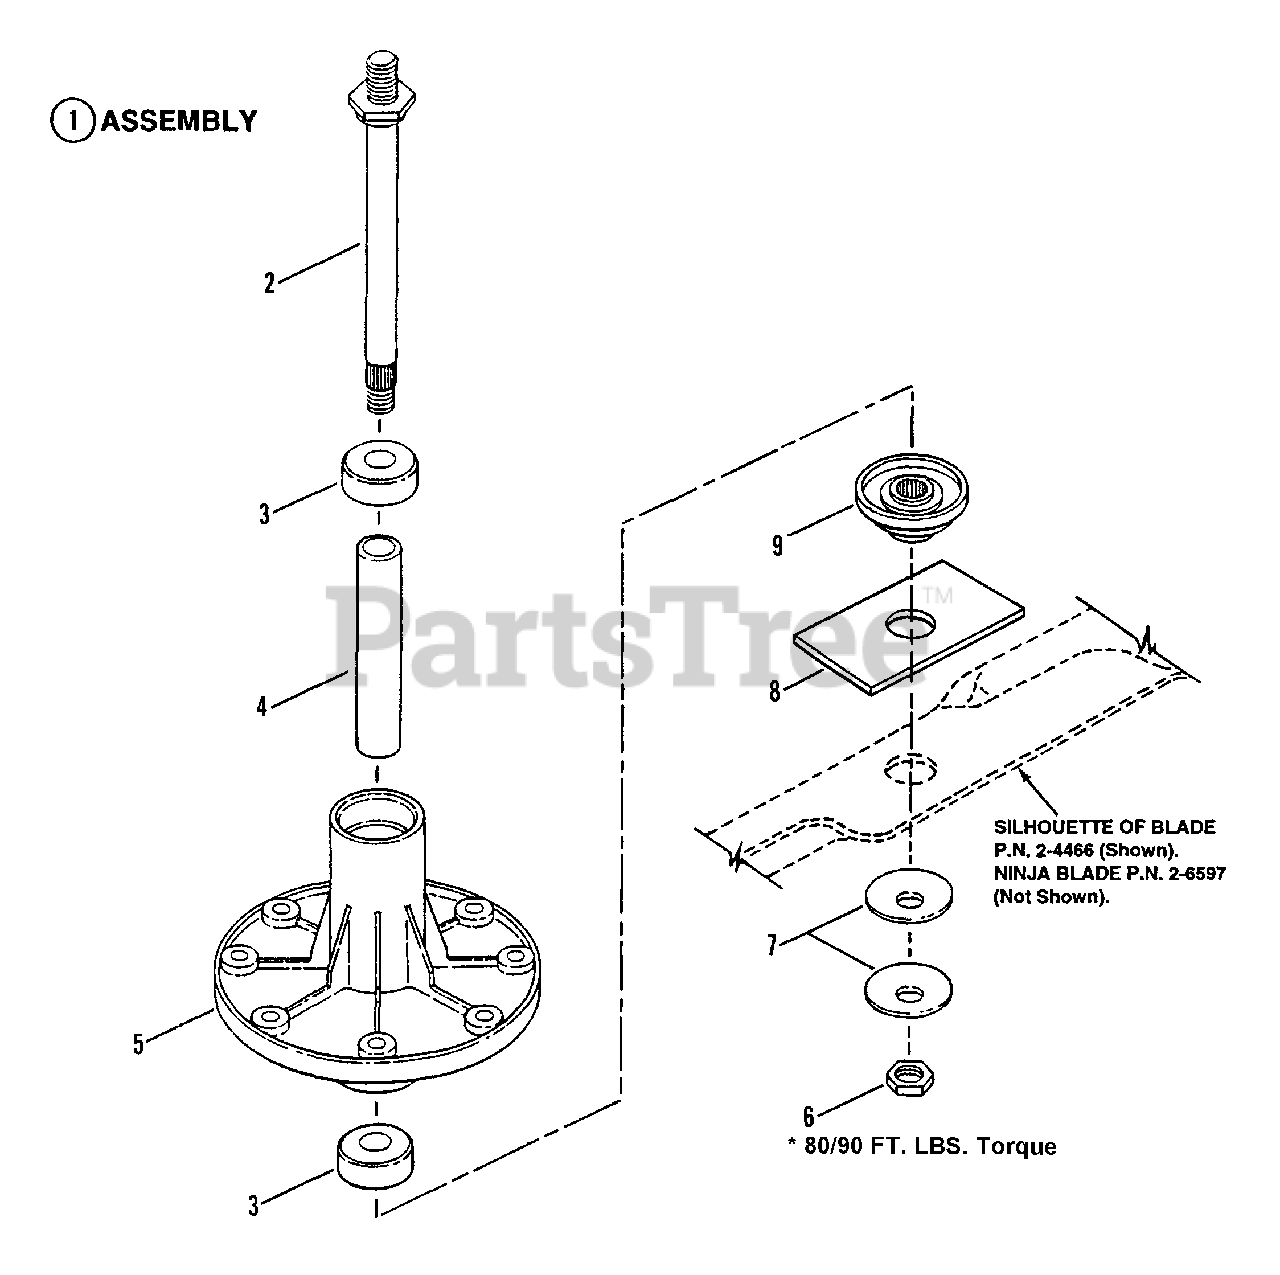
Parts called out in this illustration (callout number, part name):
1	ASSEMBLY, Spindle Housing, 38" Cutting Deck
2	SPINDLE (7.019")
3	BEARING, Spindle
4	SPACER, Spindle Housing
5	HOUSING, Spindle
6	NUT, 9/16-18 Hex Jam
7	WASHER, Bellville, 19/32" I.D. x 1 3/4" O.D.
8	WASHER, Ninja Blade
9	SPACER, Blade
10	BLADE, Standard 19-1/2"
